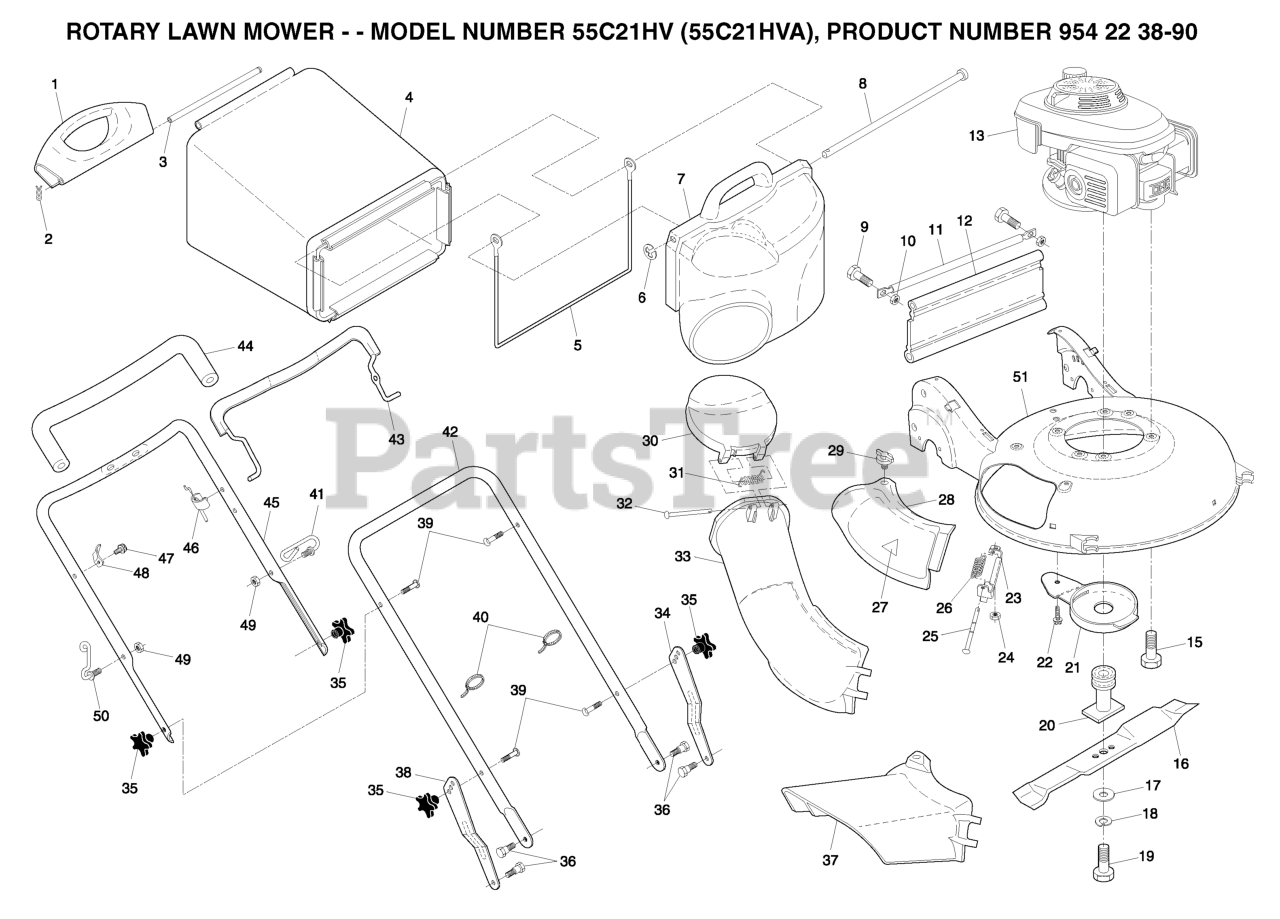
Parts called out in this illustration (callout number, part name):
1	HANDLE.GRASSBAG.REAR.H-GRAY
2	COTTER PIN (3 2)(2 2MC)
3	ROD.REAR.HANDLE.YELLOW
4	GRASSBAG
5	FRAME, GRASSBAG
7	DOOR, GRASSBAG
8	ROD, PIVOT
10	LOCKNUT.NYLOC.1/4-20
11	TUBE, REAR SKIRT
12	SKIRT, REAR
15	BOLT 3/8-16X1-1/8
16	21" MULCH BLADE PREMIUM
17	WASHER,HARDEN
18	LOCKWASHER
19	SCREW.HX.HEAD.3/8-24
21	DEBRIS SHEILD
22	SCREW 1/4X20
23	BRACKET.ASM.HINGE
24	LOCK NUT
25	ROD.HINGE.1/4"3.82"
26	SPRING.MULCH.DOOR
27	DECAL HYT
28	MULCHER DOOR
29	KNOB.MULCH.DOOR
30	CHUTE.DOOR.21.HV.H-GRAY
32	ROD.HINGE.1/4"3.82"
33	DISCHARGE CHUTE PLASTIC
35	KNOB.HANDLE.STAR.HUSQ.GRAY
36	SHOULDER BOLT
37	GUARD.CLIP.ON.21.HV.GRAY
39	HANDLE BOLT
40	TIE GUIDE
42	HANDLE.LOWER.GREY
43	BAIL CONTROL
44	GRIP.HANDLE.FOAM.WIDE.(1 SIDE)
45	HANDLE.ASM.UPPER.W/GRIP
46	ASSY ZONE CONTROL
48	BRACKET
50	GUIDE.ROPE.WALK.MOWER
